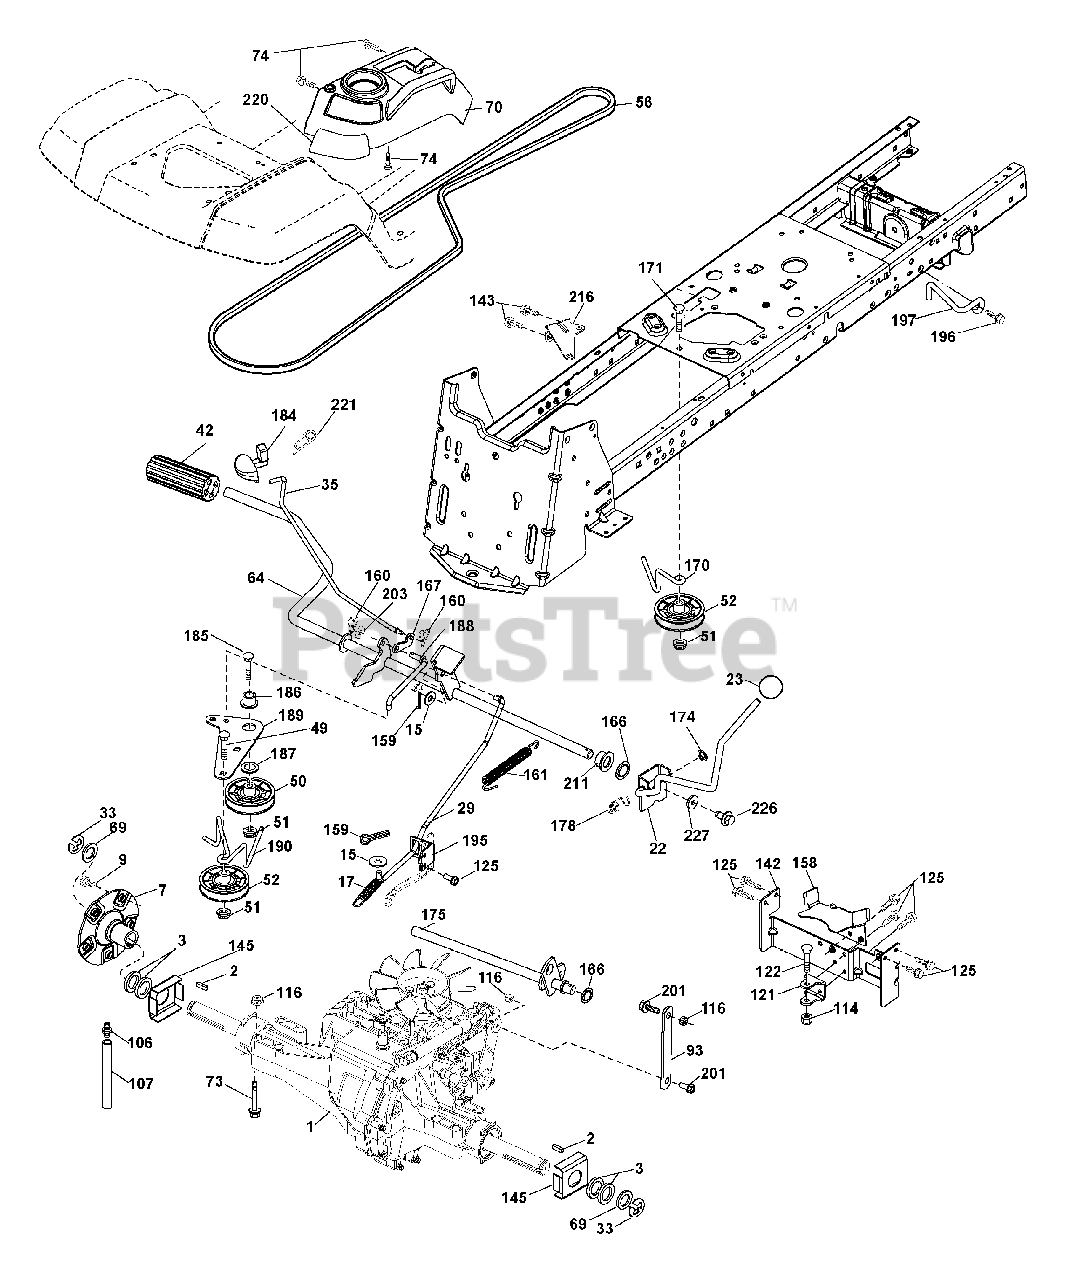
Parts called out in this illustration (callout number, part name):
1	Transaxle
2	Key 1/4 x 2.5
7	Hub Asm. Wheel
9	Bolt Hub Wheel
15	Washer 13/32 x 13/16 x 16 Ga.
17	Spring, Brake
22	Shifter Rod
29	Rod, Brake
35	Rod, Brake, Park
42	Cover, Foot Pedal
50	Pulley Idler Flat
51	Lock Nut 3/8-16
52	Idler V-Groove 910 Offset
56	V-Belt, Drive
64	Shaft Asm. Pedal Brake Control
69	Washer 11/32 x 1-5/8 x 16 Ga.
70	Control Asm.
73	Bolt Hex Flghd 5/16-18 x 3.00
74	Screw 1/4 x 1/2
93	Link Shift
106	Cap Asm. Vent
114	Nut Lock Hex w/Insert 5/16-18 unc
116	Nut Lock Hex Flange 5/16-18
121	Bracket Strap Torque
122	Bolt 5/16 - 18 x 2.50
125	Screw 5/16-18 x 3/4
142	Strap Torque
143	Screw Thdrol 5/16-18 x 1/2
145	Washer Axle flange
158	Keeper Belt
159	Pin Cotter 1/8 x 3/4
160	Retainer Clip
161	Spring, Return, Clutch
166	Nut Push .625
167	Latch Brake Parking
170	Keeper Belt Centerspan
175	Shaft Asm Shift
178	Spring Shift
184	Handle Parking Brake
185	Bolt Rdhd Sqnk 3/8-16 x 2-1/2
186	Spacer Retainer
187	Washer
188	Link Clutch Ground Drive
189	Bellcrank Ground Drive
190	Keeper Bellcrank Ground Dr.
195	Bracket Rod Brake
196	Screw 3/8-16 x 1
197	Bracket Clutch Anti-Rotation
201	Bolt Shoulder 5/16-18 unc
203	Washer 11/32 x 11/16 x 16 Ga.
216	Bracket Pulley Idler
220	Reflector RH
221	Retainer Spring Clip Handle
226	Bolt Fin Hex 7/16 - 14 x 1 GR5
227	Washer Serrated
